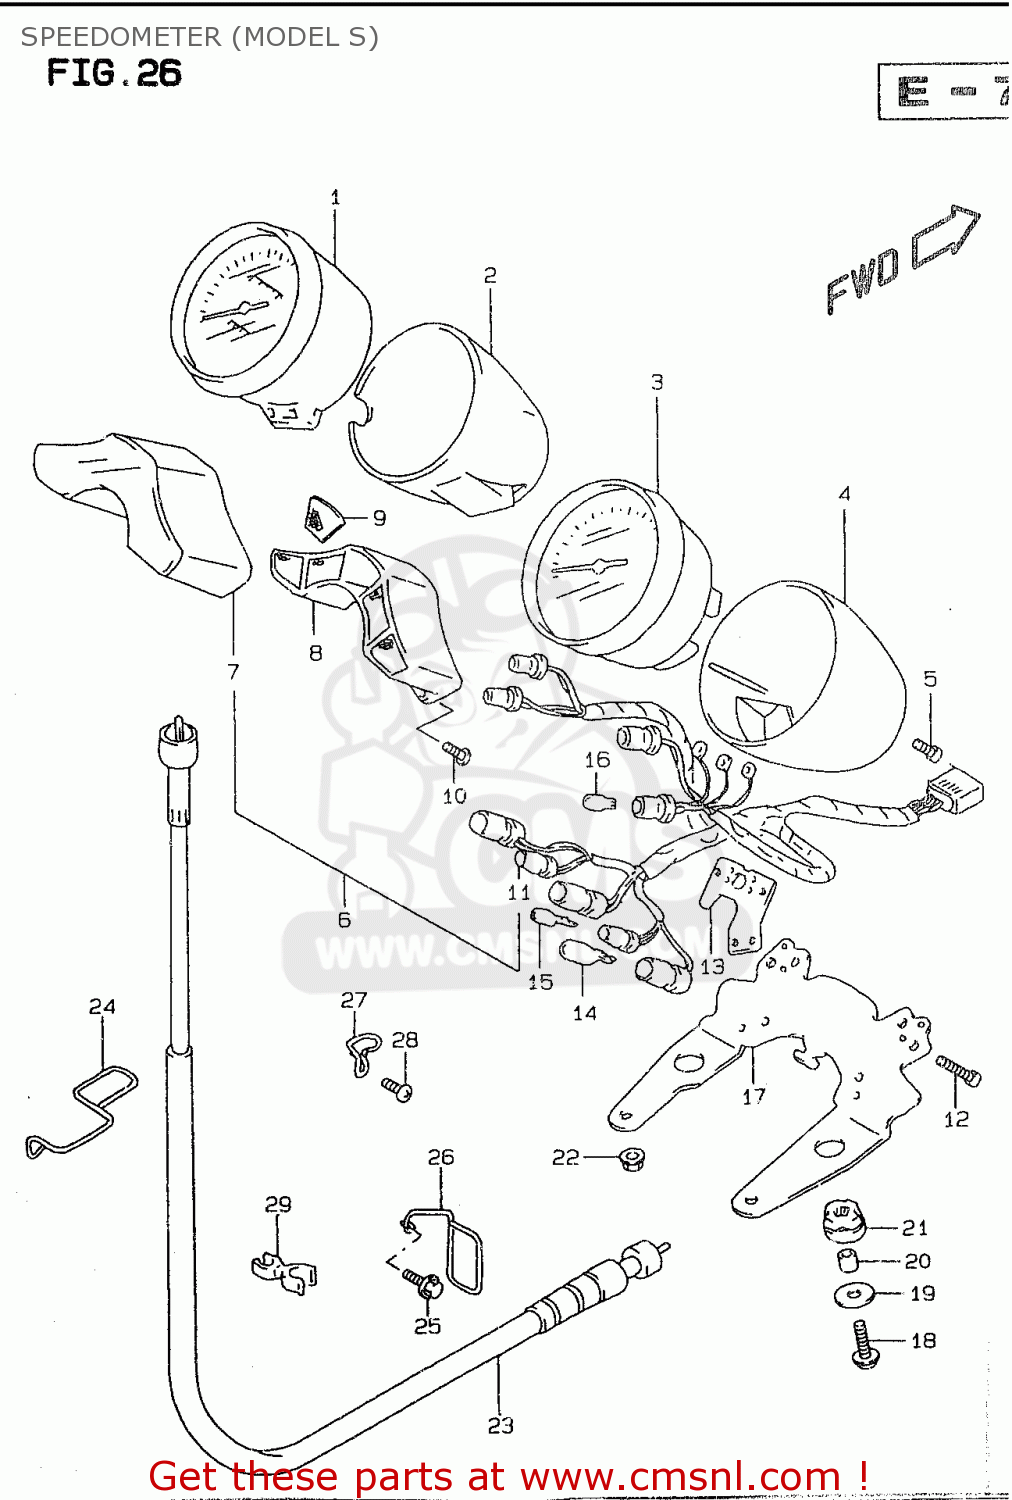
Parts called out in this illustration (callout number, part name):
1	SPEEDOMETER
2	LWR CASE,SPEEDOMETER
3	TACHOMETER
4	LOWER CASE,TAC
5	SCREW
6	BOX, PILOT
7	CASE,UPR
8	INNER CASE
9	LENS SET,PILOT
10	SCREW
11	SOCKET
12	SCREW
13	PLATE
14	BULB(12V3.4W,T10,BF175-01450A)
15	BULB(12V3W,WB371,T7)
16	BULB(12V1.7W,WB372,T7)
17	BRACKET,METER
18	BOLT
19	WASHER(6.5X20X1.6)
20	SPACER (6.4X9X15.5)
21	CUSHION
22	NUT
23	CABLE ASSEMBLY,SPEEDOMETER
24	GUIDE,SPEEDOMETER CABLE
25	BOLT
26	GUIDE,SPEEDOMETER CABLE
27	GUIDE,METER CABLE NO.1
28	SCREW 6X10
29	CLIP
